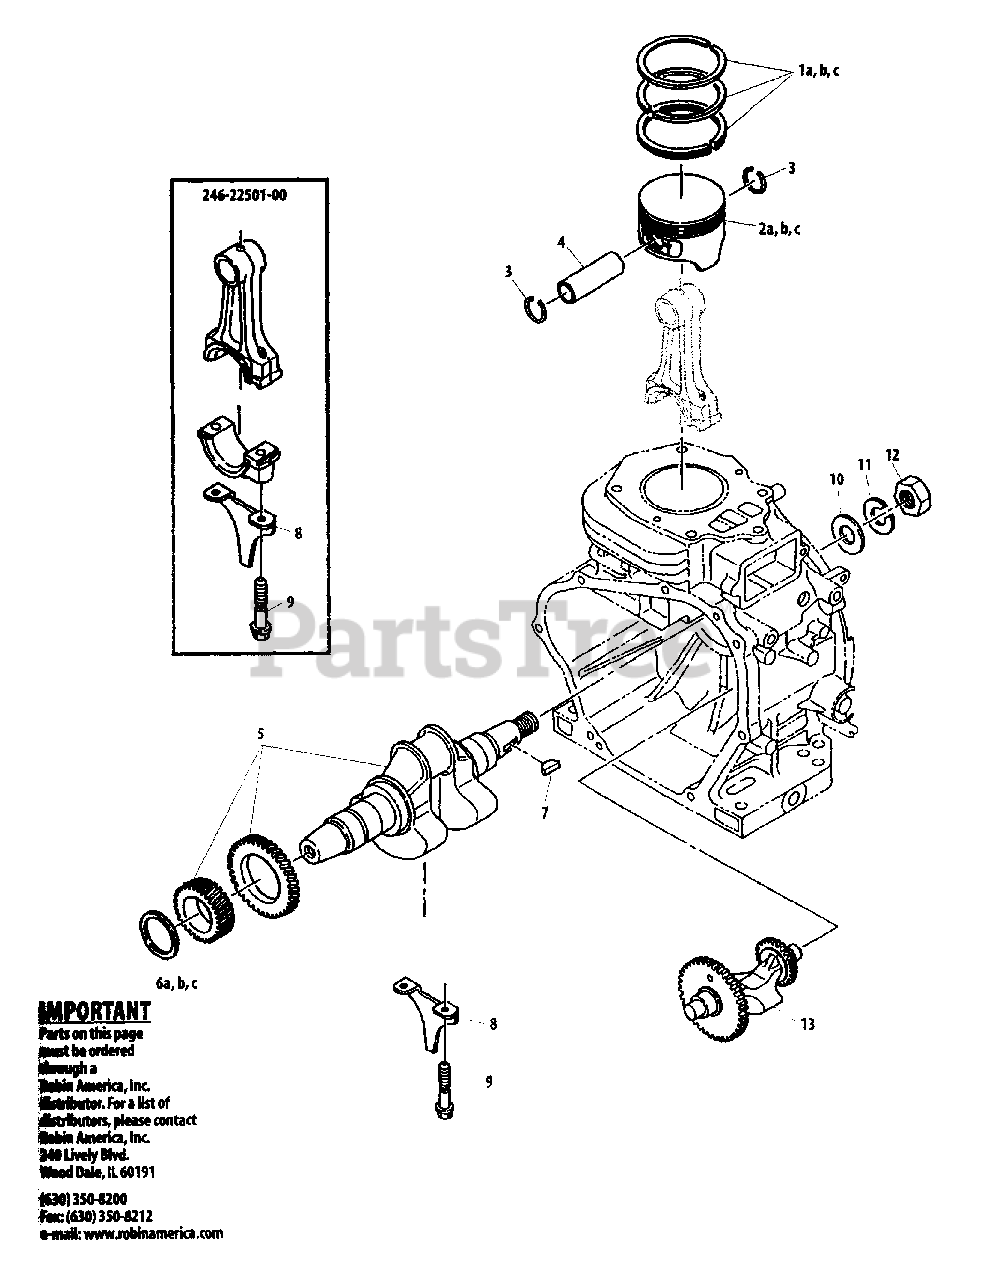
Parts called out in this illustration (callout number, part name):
1A	PISTON RING SET
1B	PISTON RING SET
1C	PISTON RING SET
2A	PISTON
2B	PISTON
2C	PISTON
3	RING, RETAINING
4	PIN, PISTON
5	CRANKSHAFT ASSY
6A	SPACER - 0.6
6B	SPACER - 0.8
6C	SPACER - 1
8	OIL SCRAPER
9	BOLT
10	WASHER
11	LOCKWASHER
12	NUT
13	SHAFT, BALANCER
